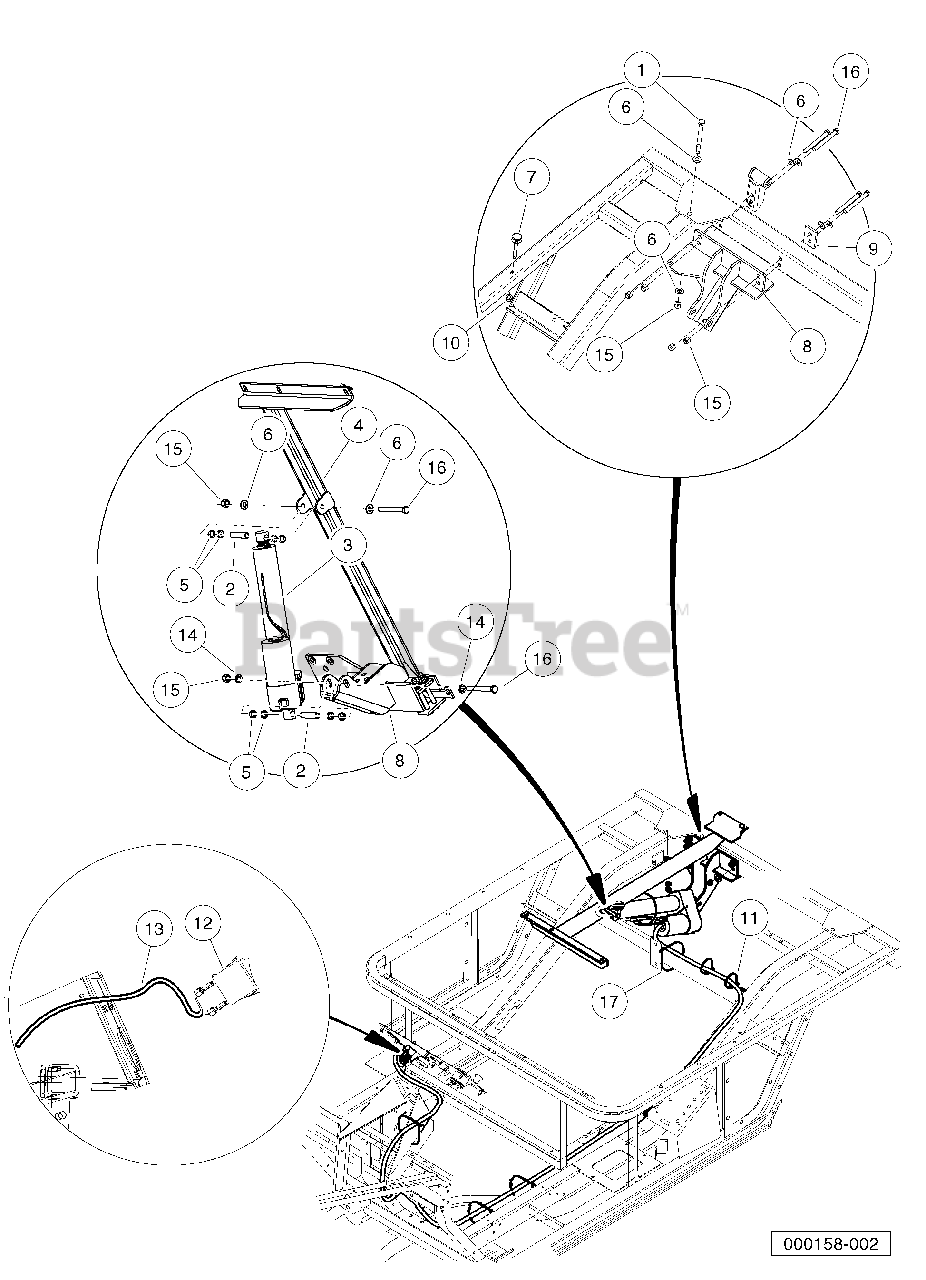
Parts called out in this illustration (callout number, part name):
1	Bolt, 3/8-16 X 4.25 Hex Head
2	Bushing Long
3	Actuator Assembly, Electric
4	Actuator Adapter
5	Body Spacer
6	Washer, 3/8 Type B Hard Flat
7	Bumper, Bed, Mtg, Front
8	Weldment, Bracket, Actuator
9	Plate, Back
10	Lock Nut, Flg M8 X 1.25 Nylon
11	Tie Wrap, 8.00" With Mount
12	Switch, Rocker, Spring Return, Bed Lift
13	Harness, AWD Bedlift
14	Washer, Lock, Hel Sp 3/8 Reg
15	Locknut, 3/8-16 Hex
16	Screw, 3/8-16 X 3.375 Hex Cap
17	Tie Wrap, 8" Nylon
